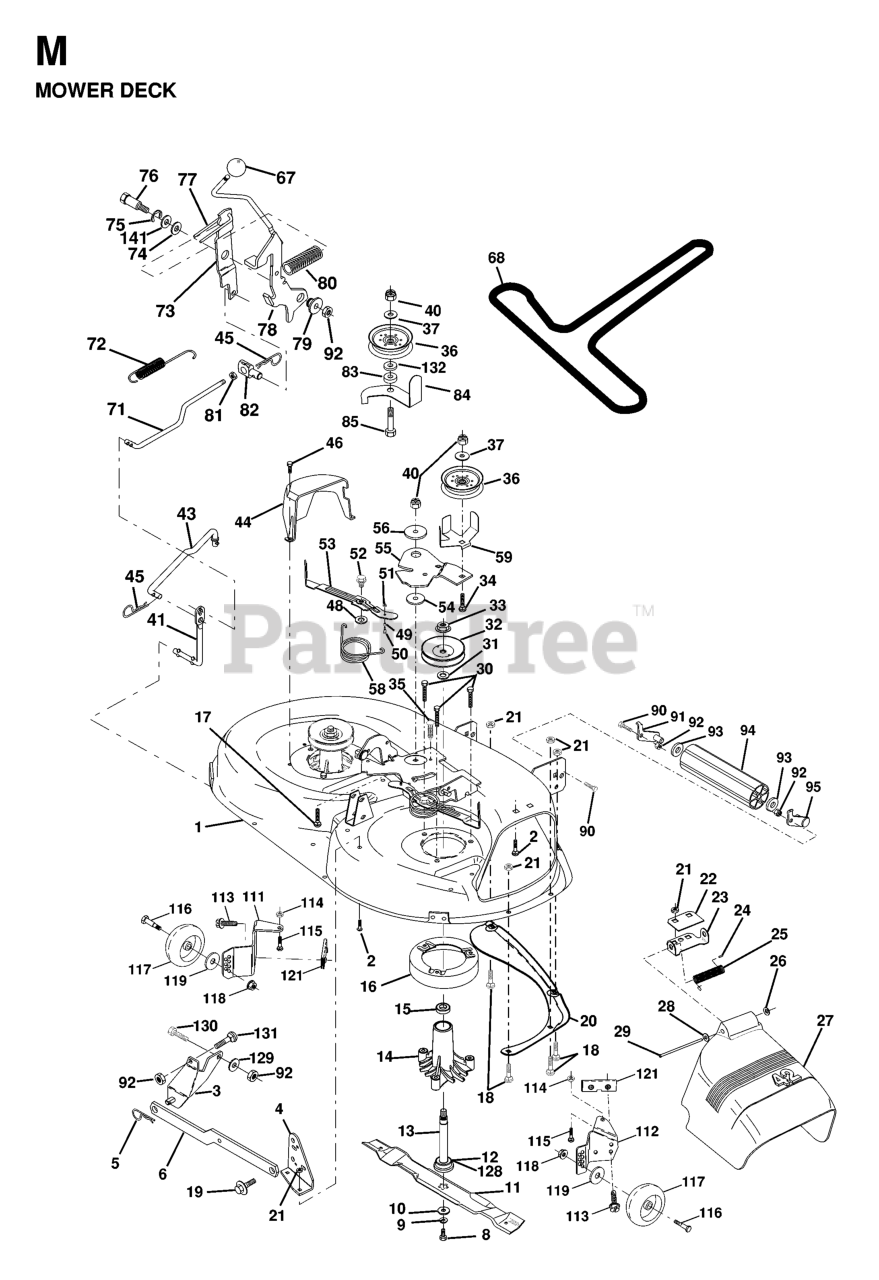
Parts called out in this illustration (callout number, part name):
1	DECK 42"
2	RP BOLT 5/16-18 X3/4 ZN/YEL GR
3	BRKT ASM SWAY BAR
4	BRKT DECK SW BAR
5	RETAINER-SPRNG RB
6	REAR SUSP ARM
8	BLADE BOLT
9	LOCKWASHER
10	WASHER.BLADE
11	BLADE 42", YTH 160
12	BEARING.BALL.#6204.(MANDREL)
13	SHAFT ASM VENT
14	HOUSING.MANDREL.VENTED (MACHD)
16	STRIPPER
17	BOLT
18	BOLT
19	BOLT SHD 5/16-18
20	BAFFLE.VORTEX
21	LOCKNUT
22	STIFFENER BRACKET
23	DEFLECTOR BRACKET
24	CAP-SLEEVE LT
25	SPRING TORSION
26	NUT PUSH M
27	SHIELD.DEFLECTOR.MOWER.42".BLK
28	Washer 11/32 x 5/8 x 16 Ga SD
29	ROD.HINGE
30	SCREW THDROL ROLLING WASHER HD
31	WASHER
32	PULLEY/MANDREL
33	NUT
35	FASTENER.XMAS.TREE
36	FLAT IDLER PULLEY
37	WASHER
43	CLUTCH ROD
44	GUARD MANDREL LH BLACK
45	RETAINER M
46	SCREW.1/4-20X5/8
49	ROLLER ASSY
52	BOLT.SHOULDER.5/16-18
53	ARM ASM PAD BRAD
54	HARDENED WASHER
55	ARM IDLER 42" MOWER LT/YT
56	SPACER RETAINER
59	GUARD, BELT
67	KNOB.CONTROL.7/16
71	CLUTCH ROD
72	RETURN SPRING
73	ARM CLUTCH SECONDARY
77	KEEPER SPRING
78	CLUTCH LEVER ASSY
79	BUSHING.FLANGE.E-RING.GROOVE
80	SPRING-CLUTCH (2 2 PW01)
81	NUT
82	TRUNNION.ADJUSTABLE.3/8-16
84	KEEPER.BELT.IDLER
85	BOLT
90	BOLT
91	BRACKET LH (A)
92	NUT
93	Washer 1 17/32 X 7/8 X 16 Ga
94	NOSE ROLLER
95	BRACKET RH (B)
111	BRACKET WHEEL GAUGE LH 42" DK
112	BRACKET WHEEL GAUGE RH 42" DK
113	SCREW.THDROL.5/16-18X3/4.TTY
114	NUT
115	BOLT.CARR.5/16-18X1/2
116	BOLT, SHOULDER
117	WHEEL GAGE DONUT
118	LOCKNUT
119	WASHER.5/16.FLAT.STE.STD.
121	BRACKET.EXTRUDED.GAGE.WHEEL
128	WASHER FELT
129	WASHER
131	BOLT D
132	Washer 13/32 x 1-3/8 x 13 Ga.
141	THRUST WASHER
